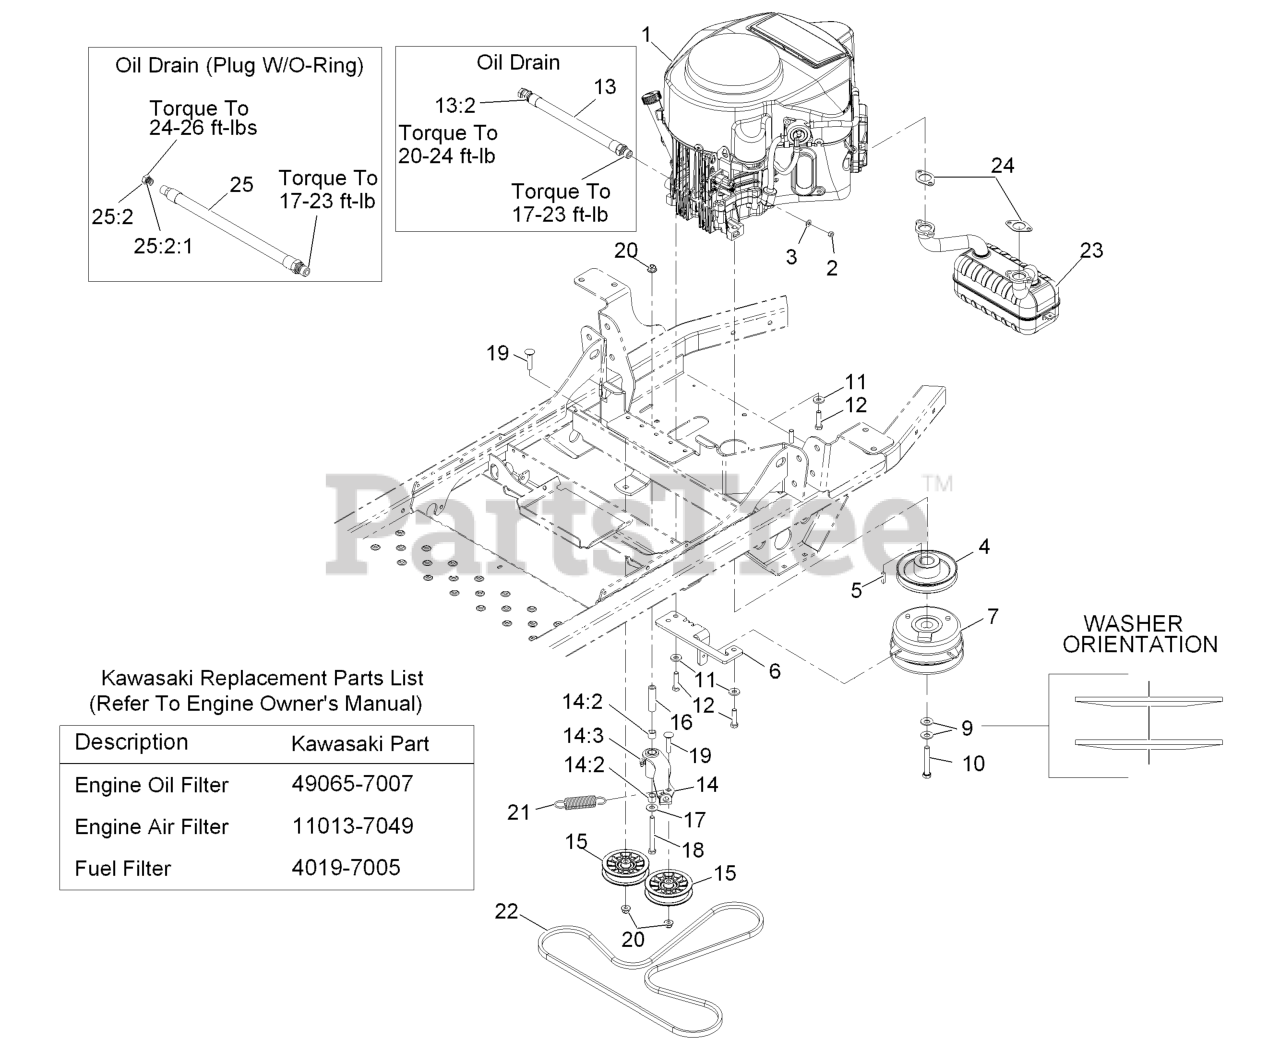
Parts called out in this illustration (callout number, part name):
2	NUT-HEX
3	WASHER-FLAT
4	SHEAVE-SPLIT STEEL
6	ANCHOR-CLUTCH
7	CLUTCH,125FTLB 1.0 B
9	WASHER-SPRING
10	SCREW-HH W/LOCTITE
11	WASHER-BELLEVILLE
12	SCREW-HH
14:2	SLEEVE-BEARING
14:3	FITTING-GREASE, 90 DEG
15	PULLEY-FLAT IDLER
16	BUSHING-PIVOT, IDLER
17	WASHER-FLAT
18	SCREW-CARR
19	SCREW-CARR
20	NUT-HF, NI
21	SPRING-EXTENSION
22	V-BELT
23	MUFFLER-KAWASAKI
24	GASKET-EXHAUST
25	ENGINE OIL DRAIN HOSE ASM
25:2	PLUG-HH
25:2:1	O-RING
